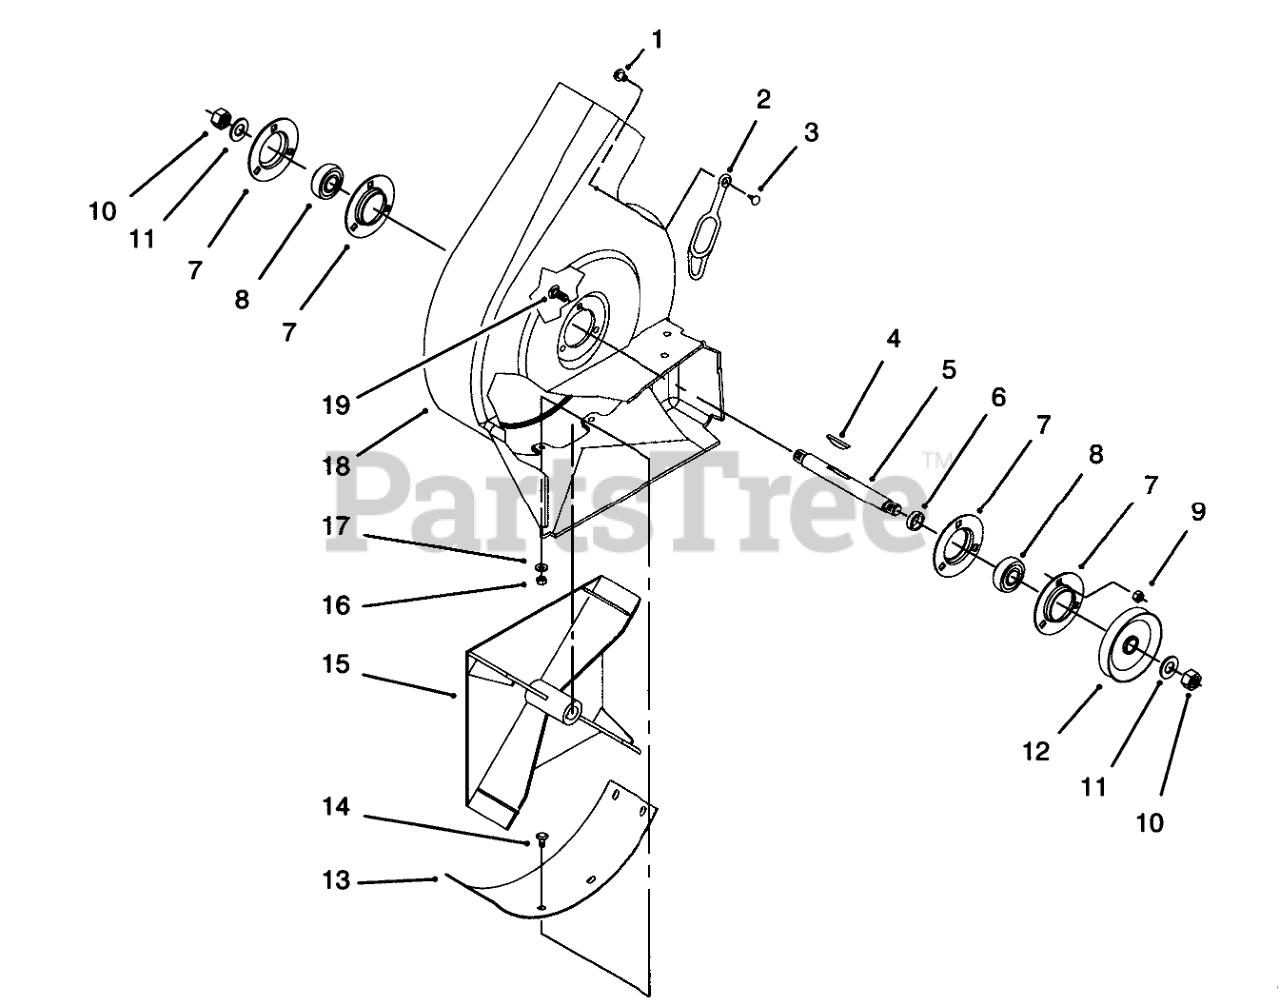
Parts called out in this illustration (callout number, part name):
1	SPACER-INTERLOCK
2	RETAINER-DUCT
3	FASTENER-PANEL
5	SHAFT-BLOWER
6	Spacer
7	FLANGE
8	BEARING-BALL
9	NUT-HF
10	NUT-JAM
11	WASHER-LOCK
12	PULLEY-BLOWER
13	COVER-BLOWER, BOTTOM
14	SCREW-CARRIAGE
15	Impeller
16	NUT-LOCK, NI
17	WASHER-FLAT
18	HOUSING-VAC, BLOWER
19	SCREW-CARR
